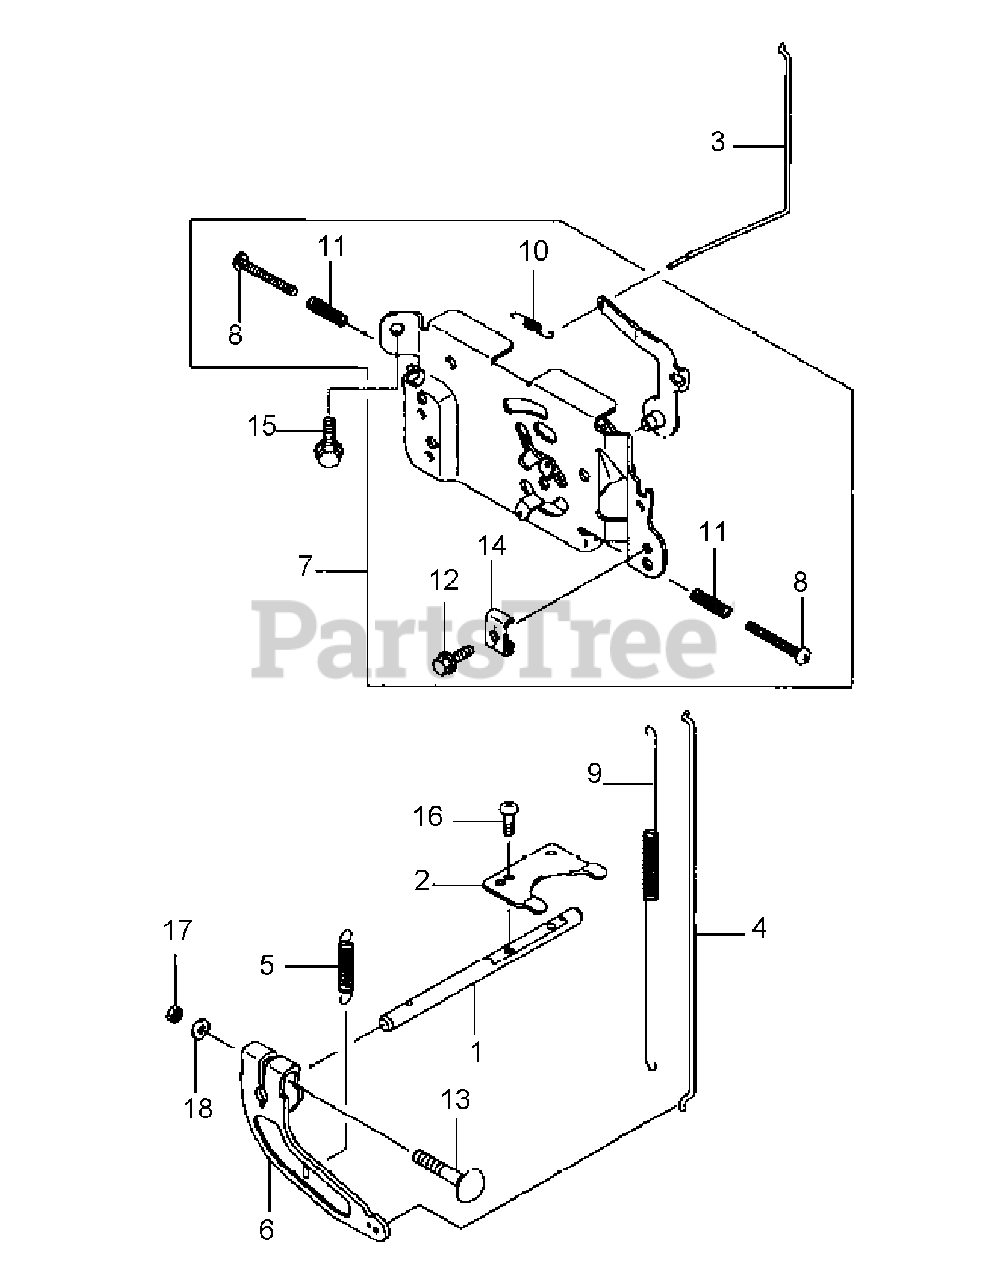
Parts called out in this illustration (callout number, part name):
5	GOVERNOR SPRING
7	CONTROL PANEL
10	SPRING
13	BOLT, 6x35
15	FLANGED BOLT
18	PLAIN WASHER
